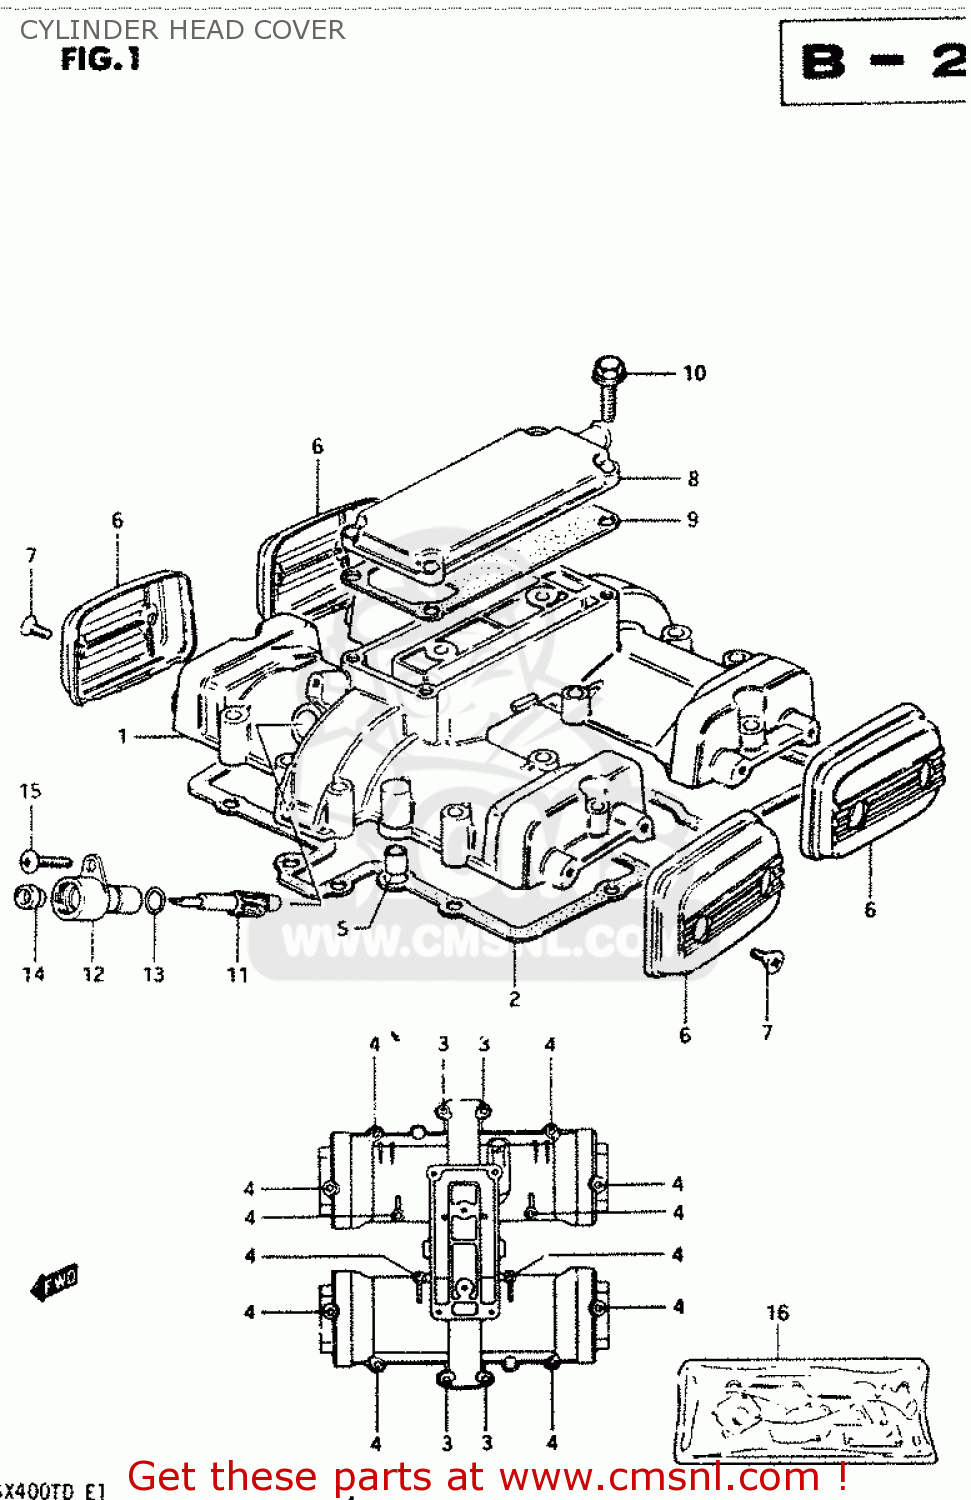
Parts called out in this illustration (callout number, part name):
1	COVER, CYLINDER HEAD
2	GASKET (MCA)
3	BOLT 6X35
4	BOLT
5	PIN(6.2X8X11)
6	CAP,CYLINDER HEAD COVER
7	SCREW(5X12)
8	COVER,BREATHER
9	GASKET (MCA)
10	BOLT,REAR
11	GEAR,TACHOMETER DRIVEN
12	SLEEVE,TACHOMETER DRIVE GEAR
13	SEAL,TACHOMETER DRIVEN
14	SEAL,OIL(5X12X8)
15	SCREW(5X12)
16	GASKET SET (MCA)
